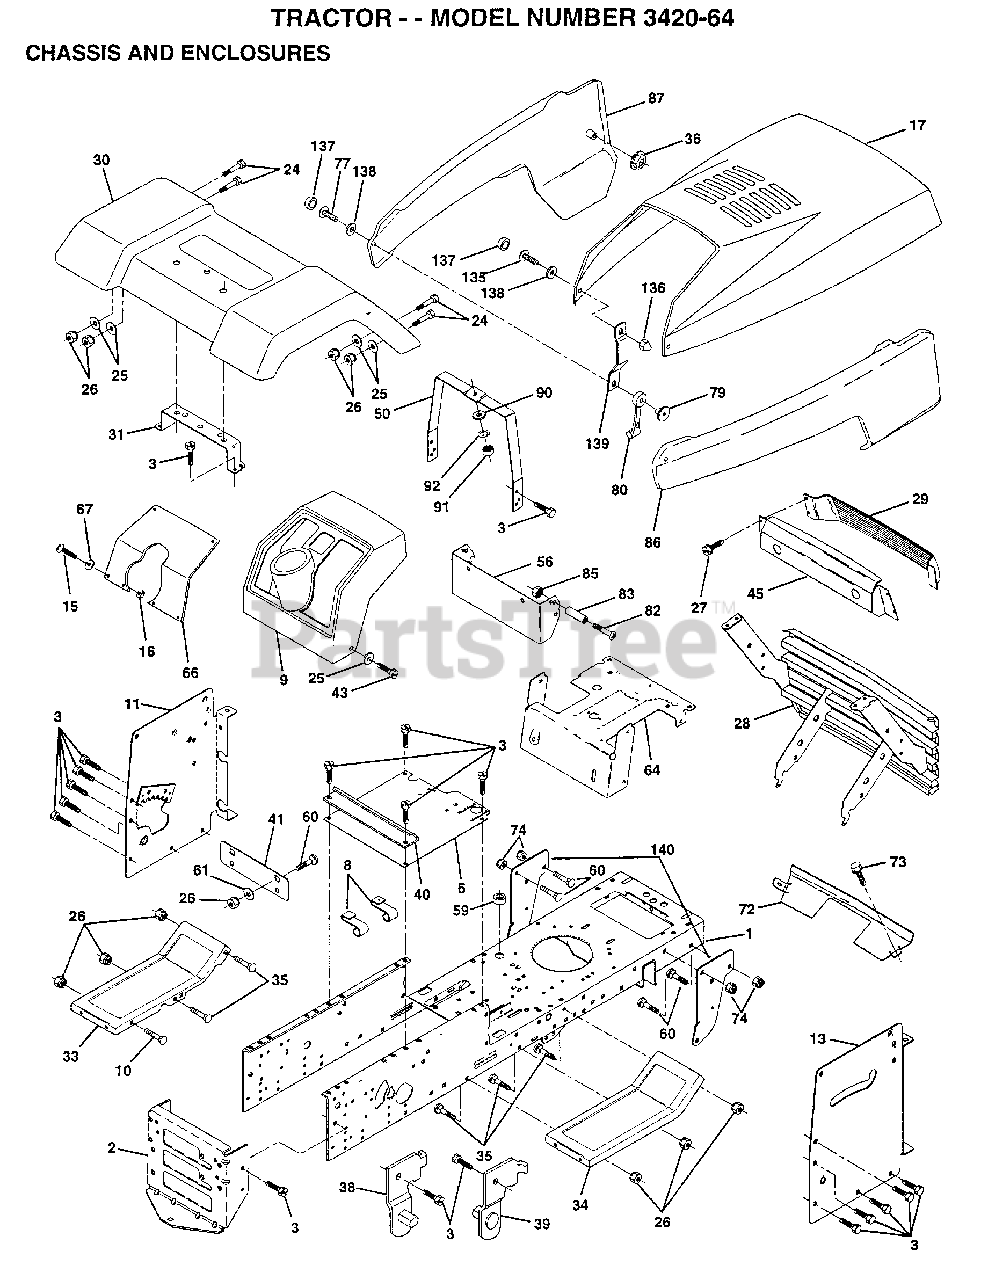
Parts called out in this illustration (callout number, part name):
1	CHASSIS WLDMT 11G
3	SCREW
8	"CLIP,INSULATOR"
9	DASHBOARD BLACK
11	PANEL.DASH.LH.PNT
13	PANEL.DASH.RH.
15	SCREW
24	BOLT
25	WASHER
26	NUT
28	GRILLE ASM PNT
29	PANEL.DASH.RH
30	FENDER LT W/SHI
31	BRACKET SUPT FEND
33	FOOTREST.LH.LT/GT
34	FOOTREST.RH.LT/GT
35	BOLT
36	PAL NUT LT
38	BRACKET ASM LH
39	BRACKET ASM RH
40	SPACER FENDER LT
41	PLATE EXTEN FEND
43	SCREW GTV
45	BEZEL.ASM.
50	DASH.SUPT.YP/HUSQ
56	EXT DASH LTYT
60	BOLT
61	WASHER
64	DASH.LOWER.LT
66	PLATE.SILKSCREEN
67	WASHER
72	STRAP PNT GRILL
73	SCREW CRT
77	SCREW
79	WELDNUT
80	HOOD LATCH T
82	SCREW
83	SPACER LT
90	WASHER PM
92	LOCKWASHER
135	SCREW.10-24X3/8.
136	ACORN NUT RB
137	SNAP CAP LT
138	WASHER LT
139	BKT.SPT.HOOD/PANL
